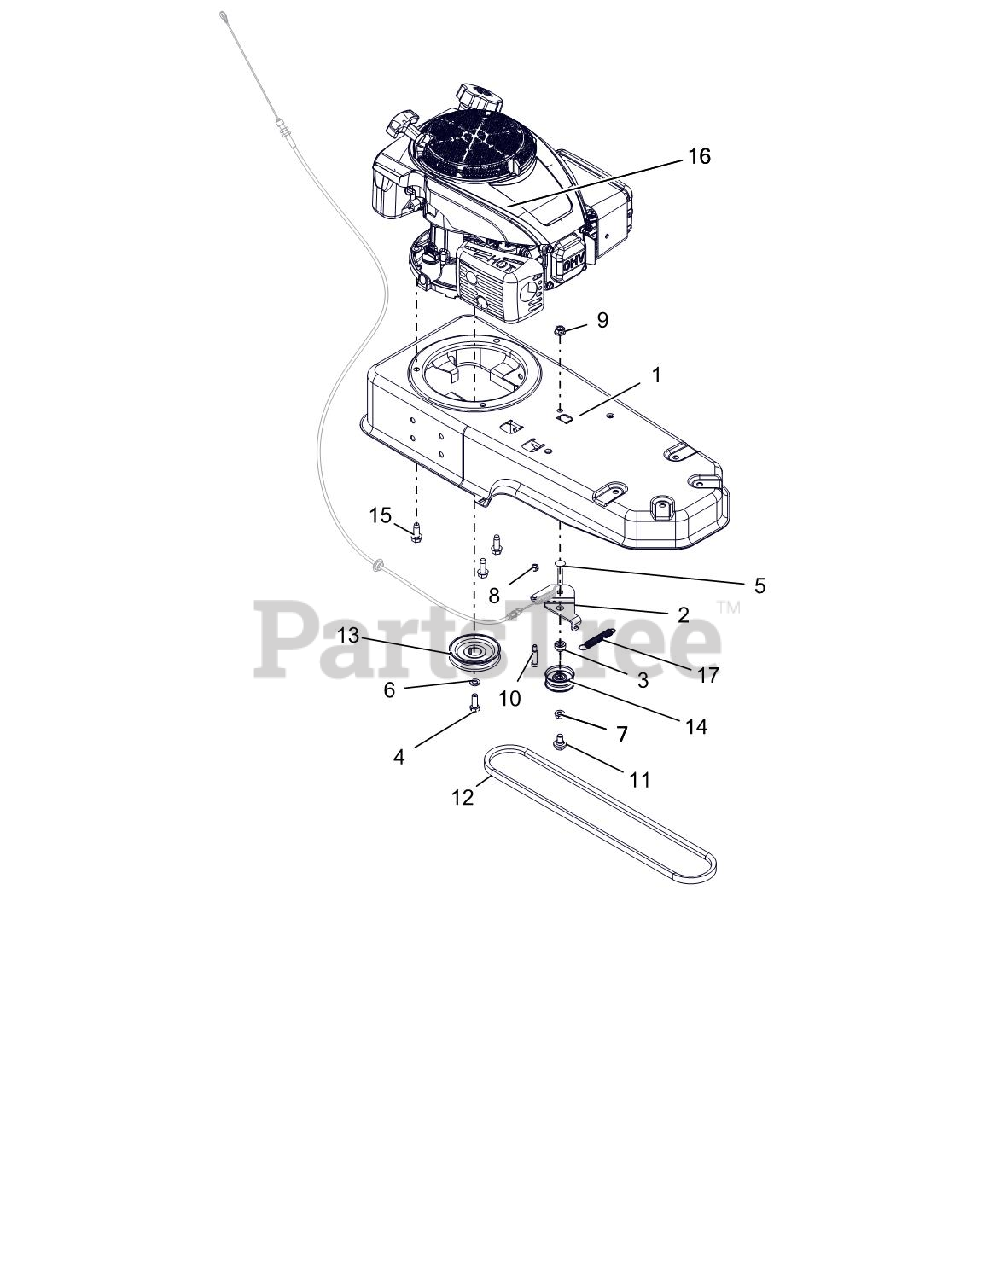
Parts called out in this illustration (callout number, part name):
1	KIT-FRAME W/SAFETY DECAL-TRIM
2	BRKT-IDLER STRING TRIMMER
3	SPCR, BRG .315X.500X.481X.281
4	BLT-HEX .38-24X1.0 YWZC GR5
5	BLT-RDHDSQSHK .31-18X1.75 YWZC
6	@WSHR-LK .38X.094 REG YWZC
7	@NUT-LK-CTR-FLG .31-18 YZ GR F
8	@NUT-LK-CTR .25-20 YWZC
9	NUT-LK-CTR-FLG .38-16 YWZC
10	SCR-SHLDR .25-20X1.00 -YWZC
11	BOLT-SHLDR .375-16X.150
12	V-BELT, HA-RAW EDGE
13	SHEAVE-ENGINE 3.50 ODX.87 WIDE
14	IDLER, FLAT - 1.875"
15	@SCR-TAP .38-16X1.00 HWH TR YZ
16	ENGINE, KOHLER XT6 149CC
17	SG-TENS .035X.45X2.75 WLD 3.5
